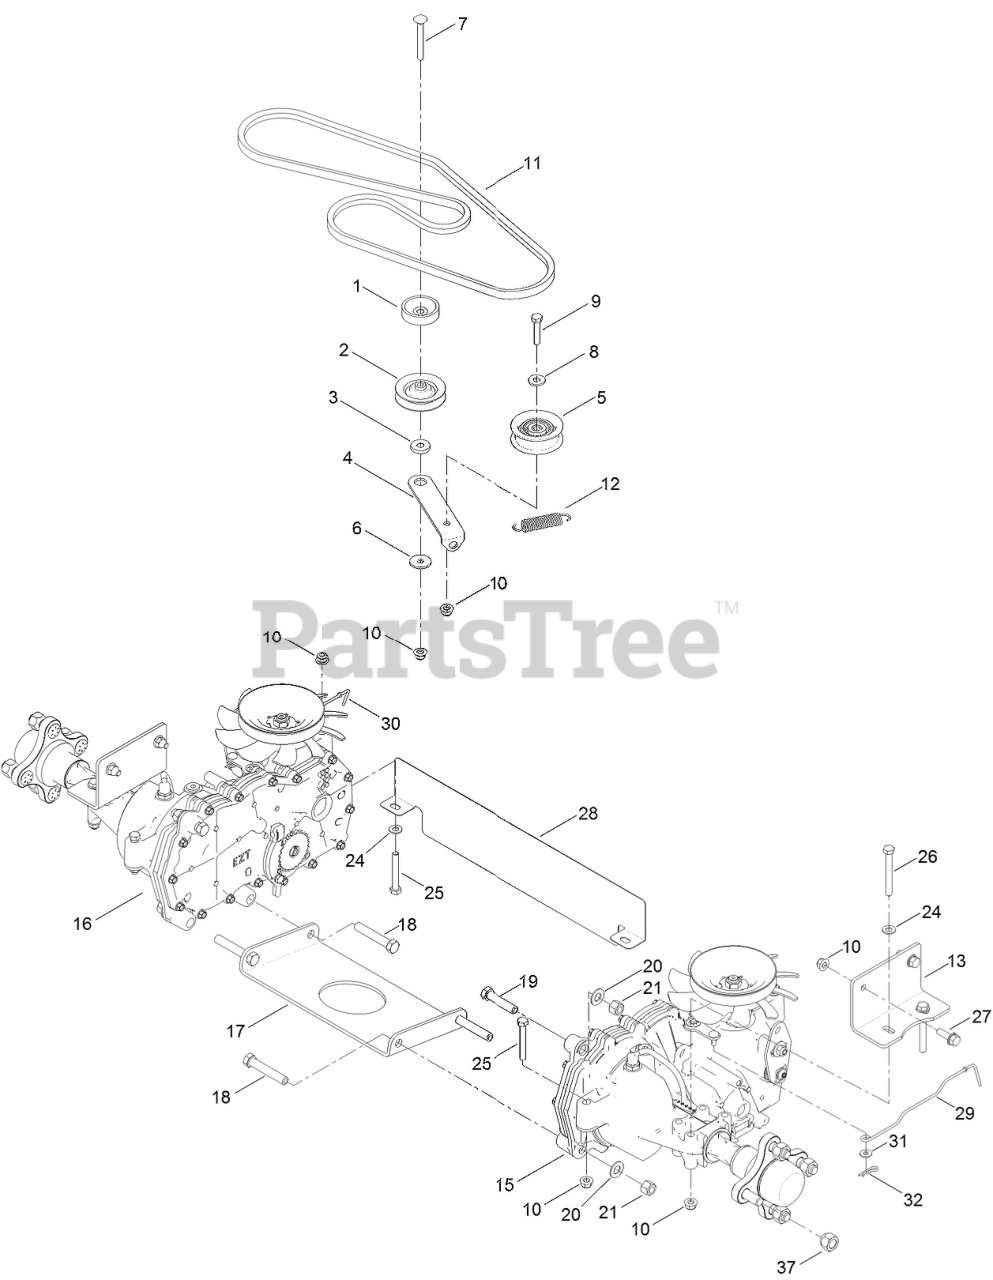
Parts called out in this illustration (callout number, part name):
1	SPACER
2	PULLEY-IDLER
3	SPACER-ARM, IDLER
4	ARM-IDLER
5	PULLEY-IDLER
6	WASHER-PIVOT
7	SCREW-CARR
8	WASHER-FLAT
9	SCREW-HH
10	NUT-HF, NI
11	V-BELT
12	SPRING-RETURN, PEDAL
13	MOUNT-HYDRO
15	LH HYDRO TRANSAXLE ASM
16	RH HYDRO TRANSAXLE ASM
17	PLATE-CROSS, HYDRO
18	SCREW-HH
19	SCREW-HH
20	WASHER-FLAT
21	NUT-LOCK, NI
24	WASHER-PLAIN
25	SCREW-HH
26	SCREW-HH
27	SCREW-HHF
28	GUARD REAR, WIDE
29	ROD-BYPASS, LH
30	ROD-BYPASS, RH
31	WASHER
32	PIN-COTTER
37	NUT-LUG
